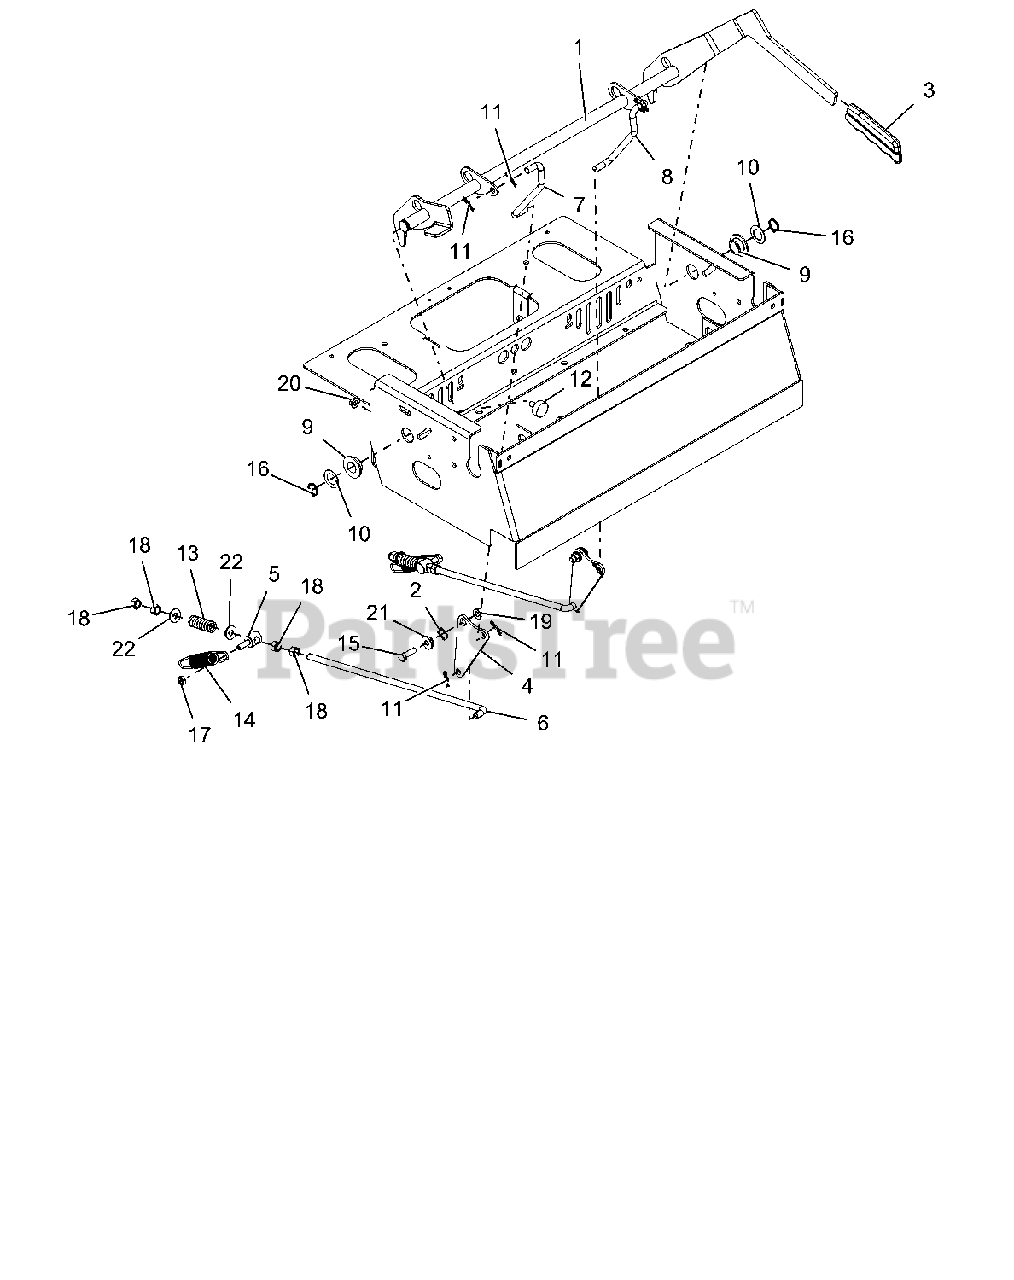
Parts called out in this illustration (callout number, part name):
1	WLDMT, PT200/400 PARK BRAKE - GAS
2	WAVE WASHER .531X.781X.125 FH
3	GRIP, PARKING BRAKE (YELLOW)
4	PLATE, BRAKE PIVOT-BLACK
5	TRUNNION, .31-18
6	ROD, BRAKE ADJ.
7	LINKAGE, RH BRAKE ACTUATING
8	LINKAGE, LH BRAKE ACTUATING
9	BSHG, FLANGE .762 X 1.48 X .44 NYLON
10	WSHR-HDND-THRST
11	PIN-HAIR, ENDRIES #25 YWZC
12	BUMPER, RUBBER
13	SPRG, COMPRESSION
14	SPRG, TENSION .105 X .850 X 4.880
15	BLT-HEX .31-18X1.00 GR5 YWZC
16	RG-RTNG-EXT .750x.078
17	NUT-LK-CTR-JAM .31-18 YWZC
18	NUT-HEX .38-16 YWZC
19	NUT, LK-TOP-FLG .312-18 YWZC
20	@NUT-SPNLK-FLG .312-18 YWZC
21	BSHG, FLG .32X.500.344X.880
22	WSHR-FL-STL.38X.875X.083 YWZC
